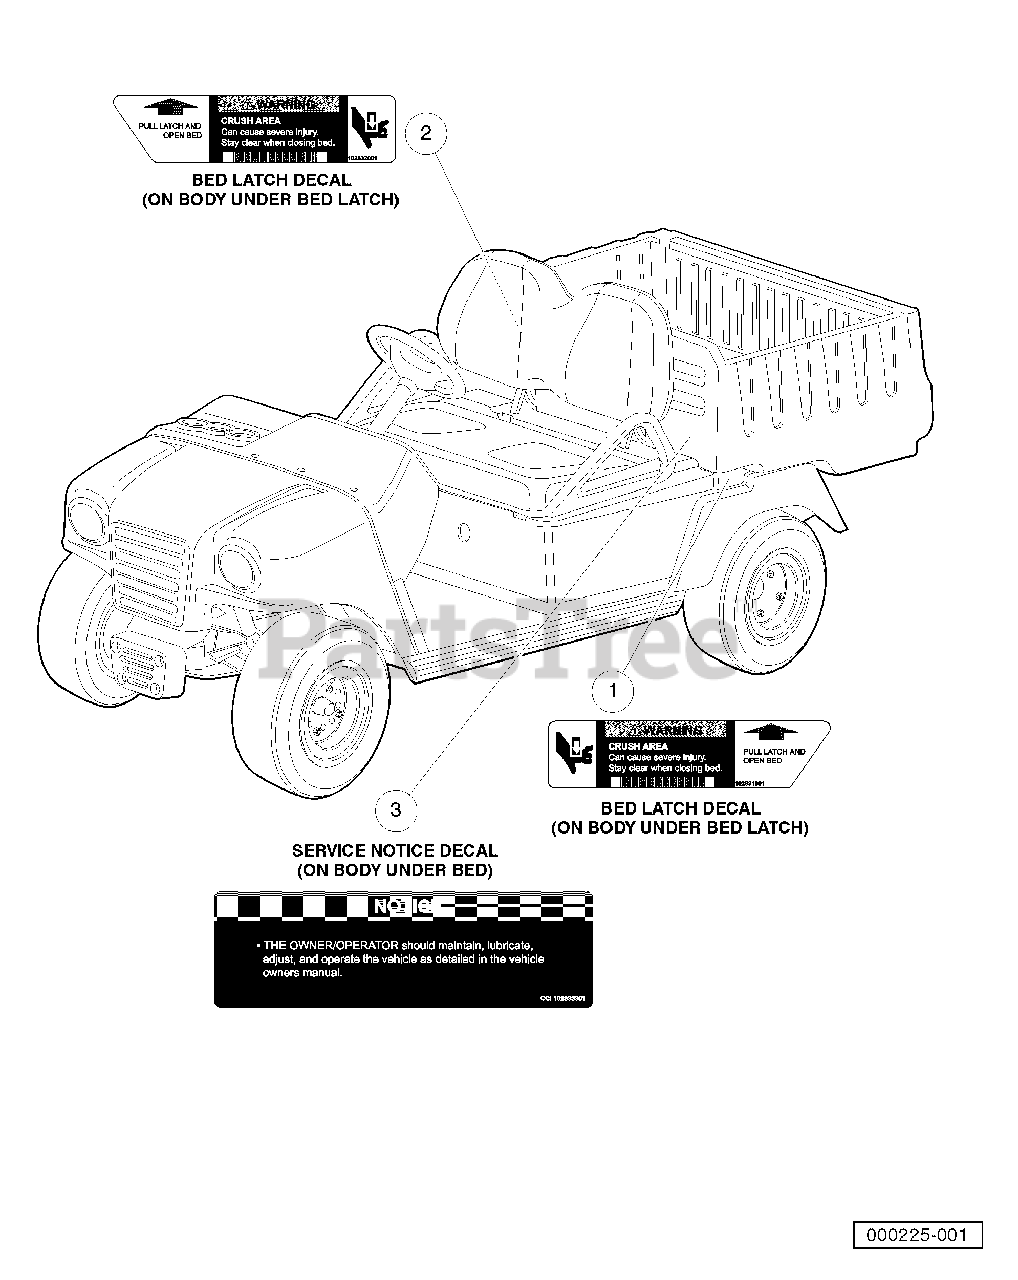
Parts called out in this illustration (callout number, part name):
1	Decal, Crush Warning, Driver-Side
2	Decal, Crush Warning, Passenger-Side
3	Decal, Maintenance
